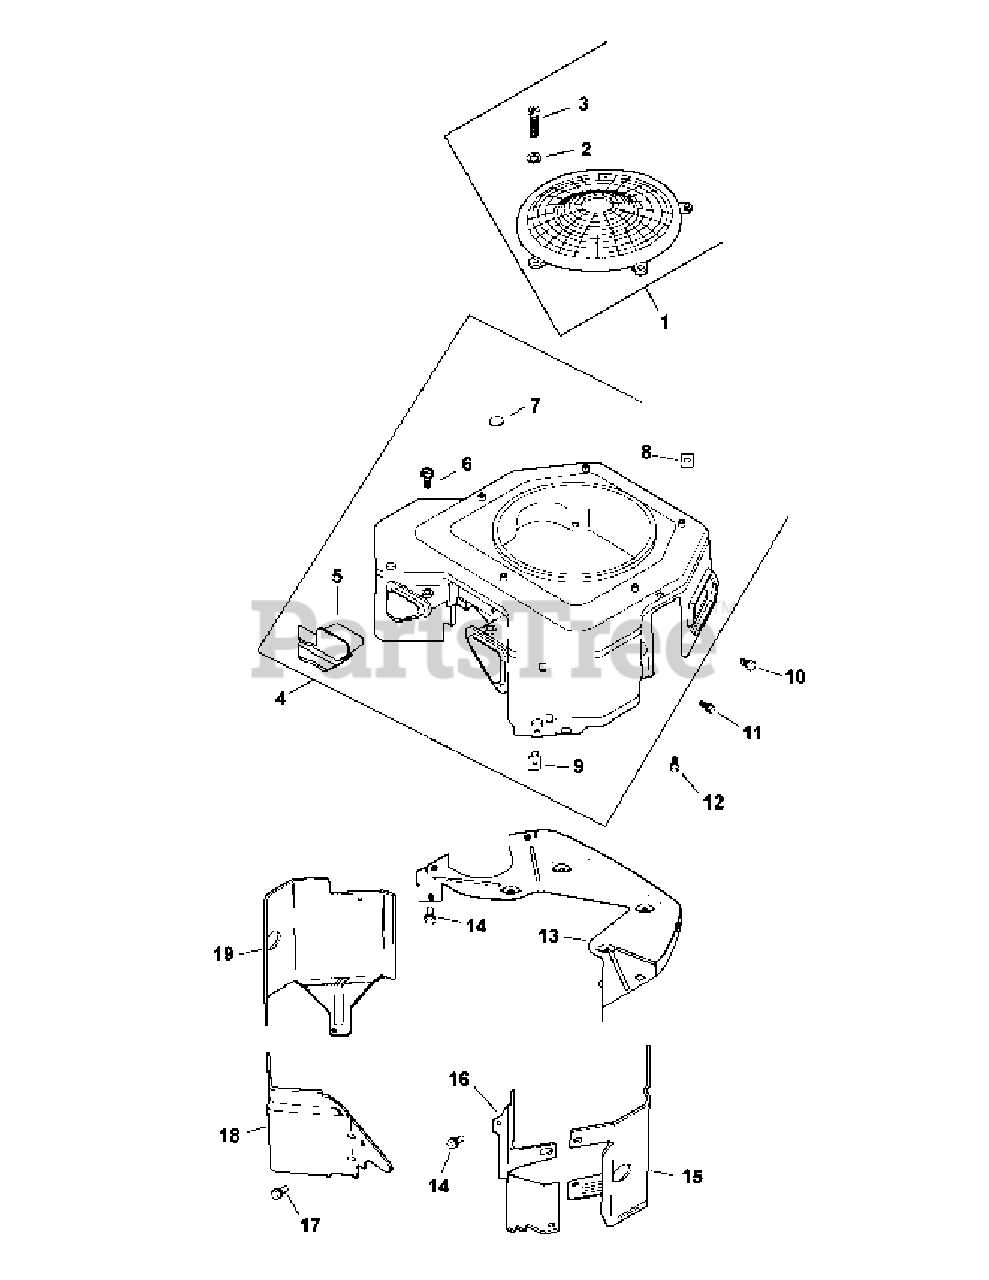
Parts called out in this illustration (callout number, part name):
1	Fixed Guard Kit
2	Flat Washer, 7/32
3	Pan Screw, M5 x 0.8 x 10
4	Blower Housing Assembly Kit
5	Blower Housing Cover
6	Tap Screw, #8-18 x 1/2
7	Button Plug, 9/16
10	Thread Forming Void Screw
11	Flange Screw, M5 x 0.8 x 16
12	Flange Screw, M5 x .8 X 20
13	Backing Plate
14	Flange Screw, M6 x 1.0 x 16
16	Valley Baffle, #2
17	Flange Screw, M5 x .8 x 10
18	Valley Baffle, #1
